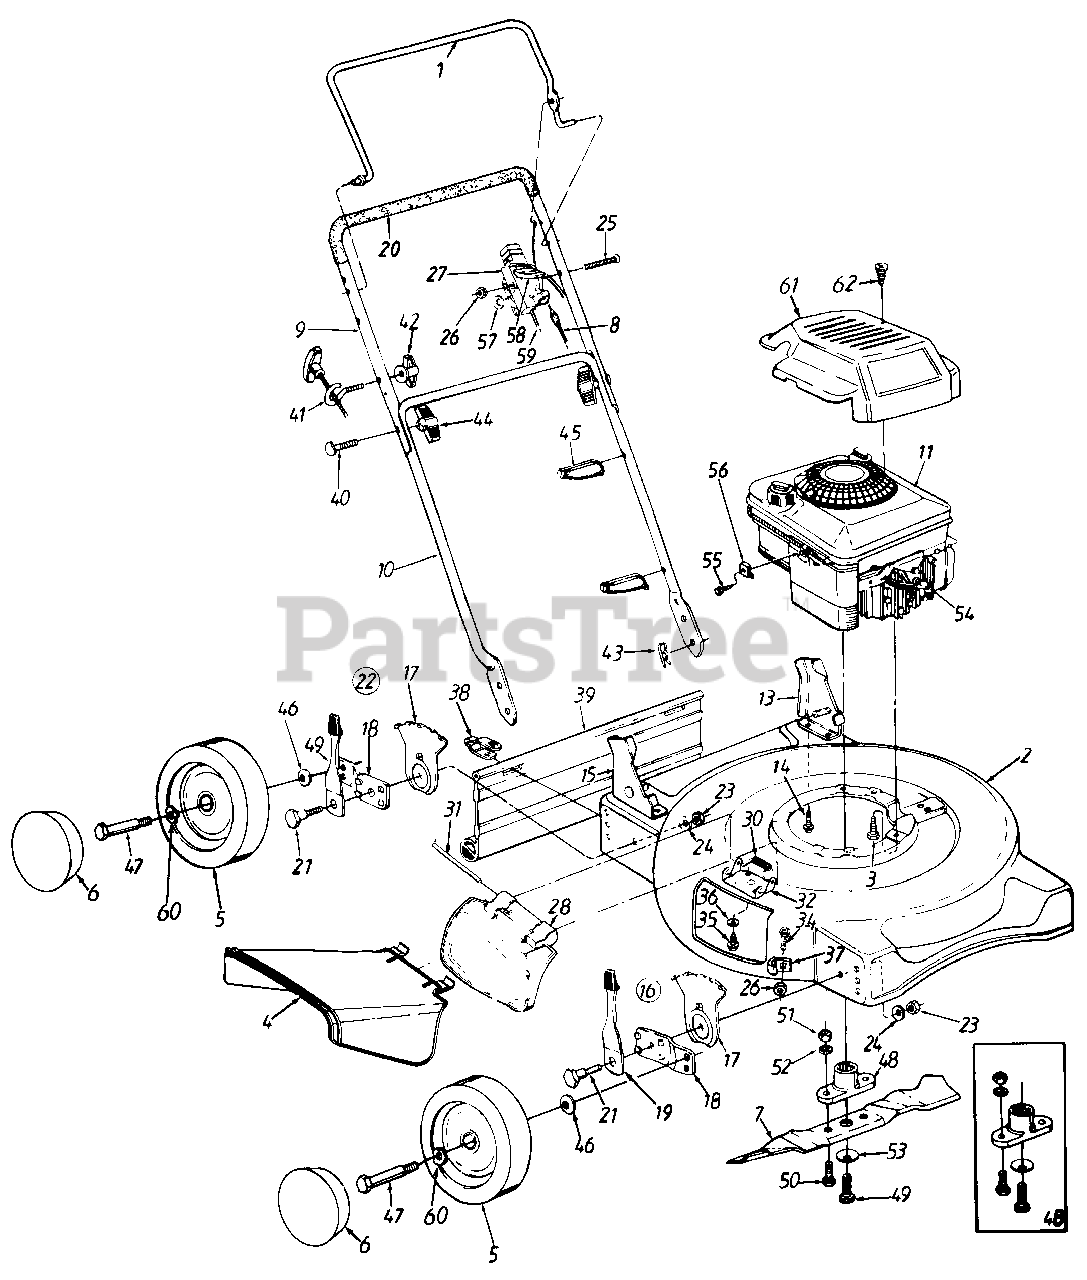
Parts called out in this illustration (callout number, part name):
1	Control Handle
2	20" Deck Assembly
3	Hex TT-Tap Scr. 3/8-16 x 1" Lg.
4	Side Chute Deflector
5	Wheel Ass'y. Comp.
6	Hub Cap
7	20" Mulching Blade
8	Control Cable-39" (Green)
11	Engine
13	Handle Brkt. Ass'y.-L.H.
14	Hex B-Tap Scr. 5/16-18 x .5" Lg.
15	Handle Brkt. Ass'y.-R.H.
16	Hgt. Adj. Ass'y.-R.H.
17	Height Adj. Plate
19	Spring Lever Ass'y. w/Knob
20	Foam Grip
21	Shoulder Bolt .5" Dia. x .434"
22	Height Adj. Ass'y.-L.H.
23	Hex Nut 3/8-16 Thd.
24	Bell-Wash. .39" I.D.
25	Oval C-Sunk Mach. Scr.
26	Hex L-Nut 1/4-20 Thd.
27	Throttle Body
28	Mulching Plug Ass'y.
30	Torsion Spring
31	Hinge Pin
34	Carriage Bolt 1/4-20 x .5" Lg.
35	Hex TT-Tap Scr. 1/4-20 x .5" Lg.
36	Bell-Wash. .265" I.D.
39	Rear Flap
40	Carriage Bolt 5/16-18 x 2" Lg.
41	Rope Guide
42	Wing Nut 1/4-20 Thd.
43	Int. Cot-Pin 5/16" Dia.
44	Handle Knob
45	Cable Tie
46	Bell-Wash. .38" I.D. x .88" O.D.
47	Axle Bolt
48	Blade Adapter Kit
49	Hex Bolt 3/8-24 x 1.5" Lg.-Gr. 5
50	Hex Bolt 3/8-24 x 1" Lg.
51	Hex Nut 3/8-24 Thd.
52	L-Wash. 3/8" I.D.
53	Bell-Wash. .39" I.D.
54	Spark Plug Boot
55	Hex Self-Tap Scr. #10-32 x .62" Lg.
56	Cable Clamp
57	Spr. Wash. .66" I.D.
58	Throttle Lever
59	Throttle Wire-51" (Red)
60	Wave-Wash.
61	Engine Shroud
62	Screw #10 x 1.25" Lg.
